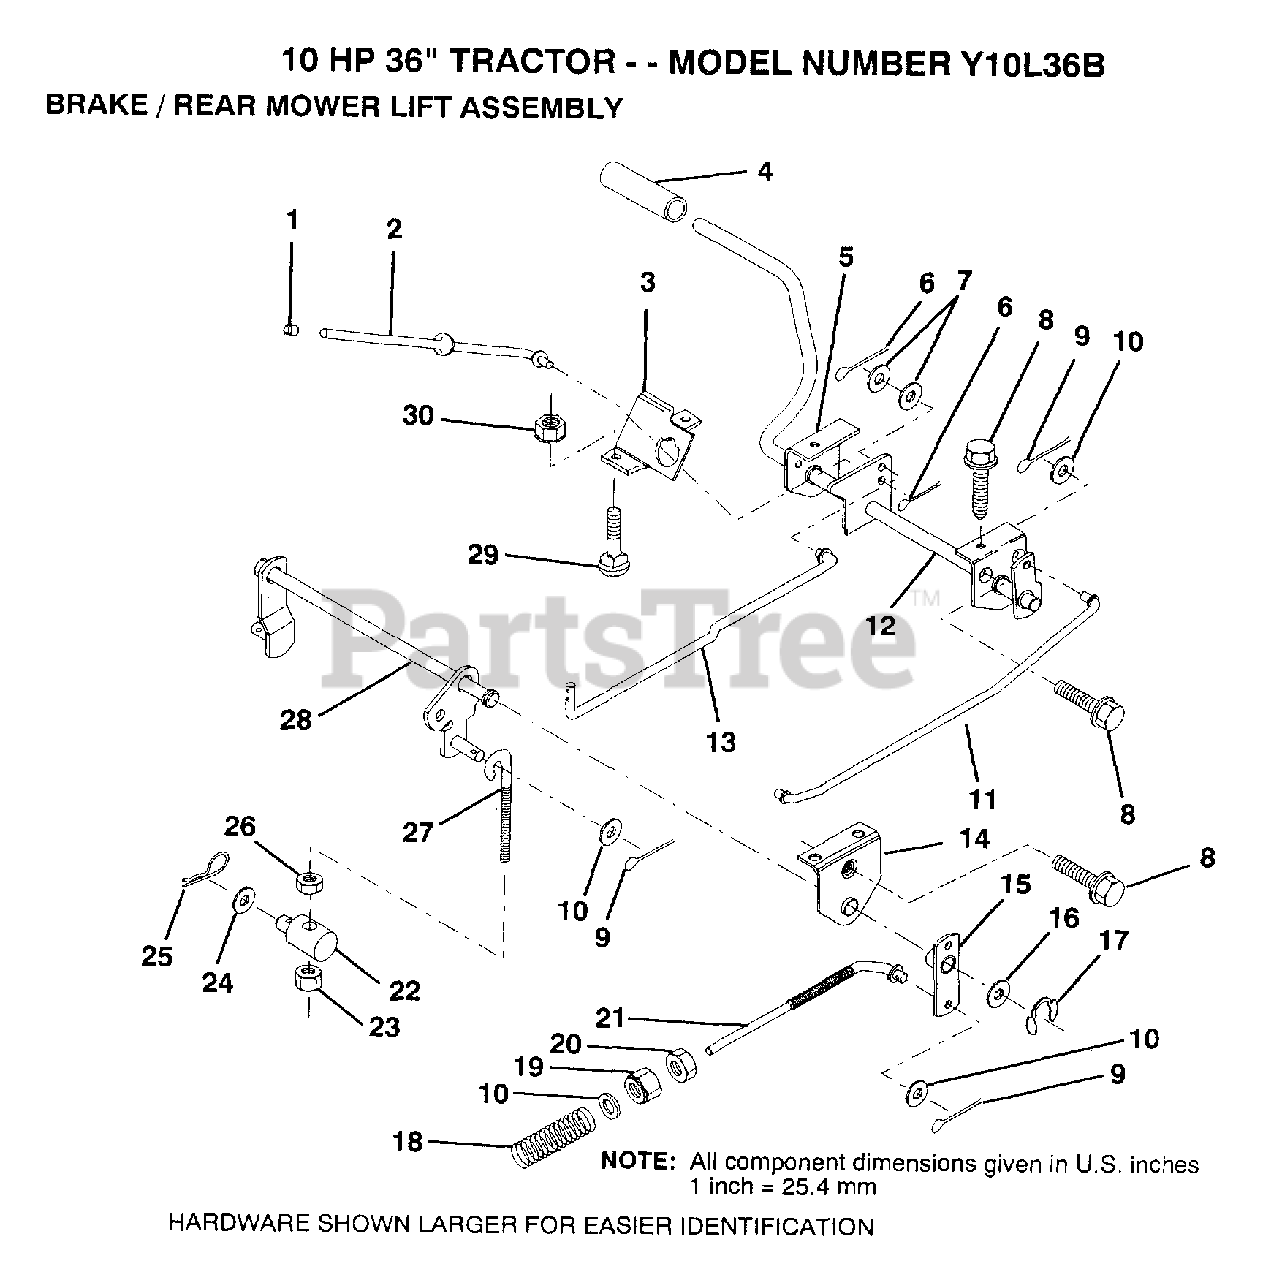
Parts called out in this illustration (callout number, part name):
1	PLUNGER CAP T
2	"ROD,PARK BRAKE"
3	"BRKT,PARK BRAKE"
4	FOOT PEDAL COVER
5	"BRKT,CLU PEDAL LH"
7	WASHER
8	SCREW LT
9	COTTER PIN
10	WASHER
11	"ROD,FRT BRAKE"
13	"ROD,CLUTCH"
14	"BRKT,LIFT SHAFT"
15	BRAKE PIVOT ARM
16	WASHER T
17	KLIP RING
18	SPRING ROD LT
19	NUT
20	NUT
21	ROD.BRAKE.REAR
24	WASHER
25	SPRING.RETAINER
26	LOCKNUT
27	"LINK, MOWER REAR"
